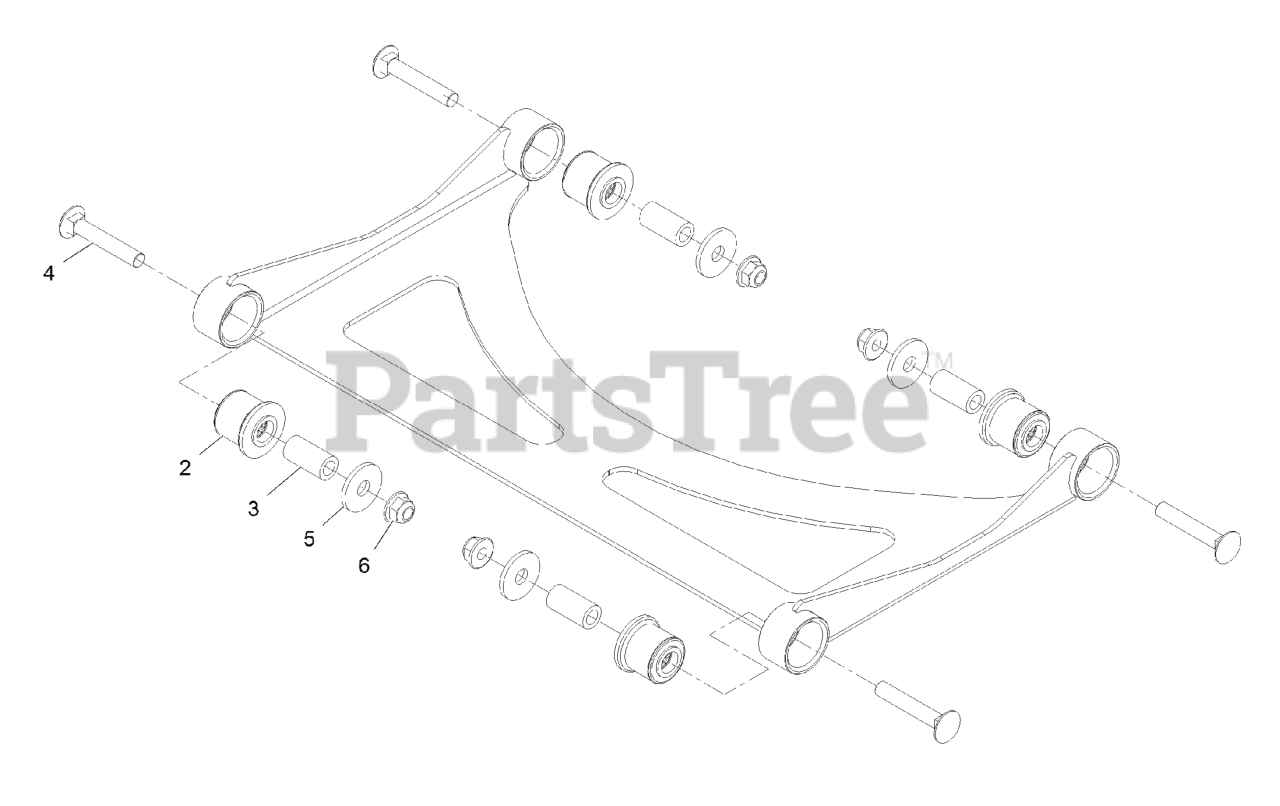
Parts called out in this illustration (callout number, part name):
2	BUSHING-RUBBER, SUSPENSION
4	Bolt-Carriage 3/8-16 X 2 1/4
5	WASHER
6	NUT-HF, NI
